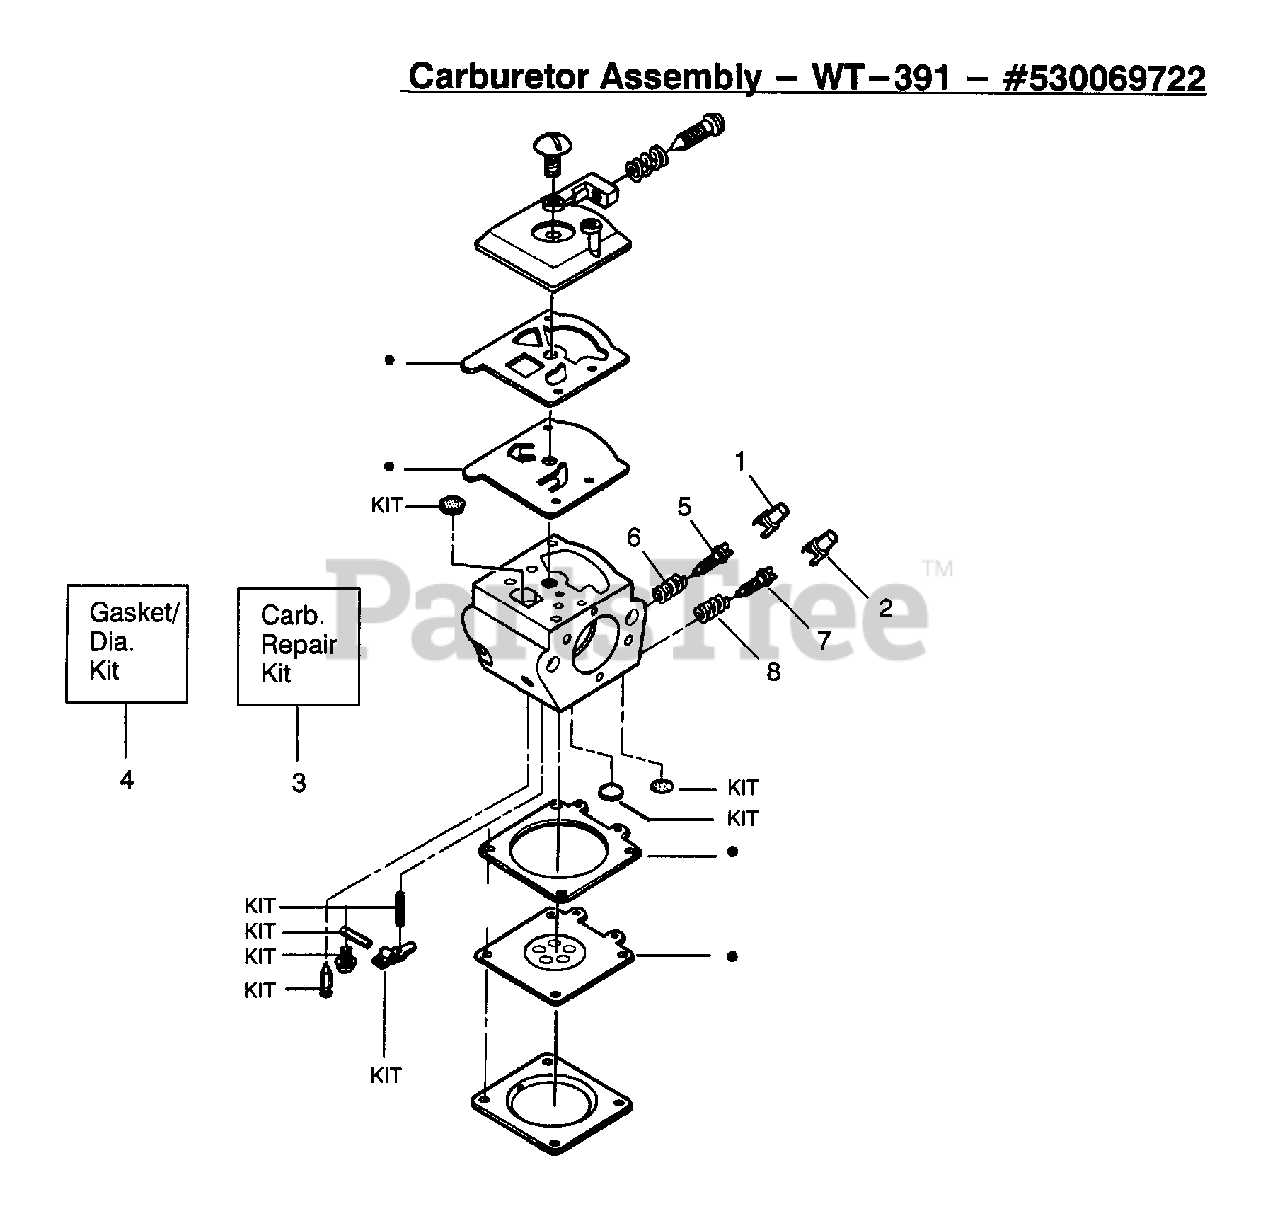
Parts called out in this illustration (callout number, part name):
2	LIMITER CAP (LOW-BLUE)
3	CARB REPAIR KIT
4	GASKET/DIAPHRAGM KIT
5	LOW SPEED NEEDLE
6	NEEDLE SPRING
7	NEEDLE HIGH SPEED
8	NEEDLE SPRING
